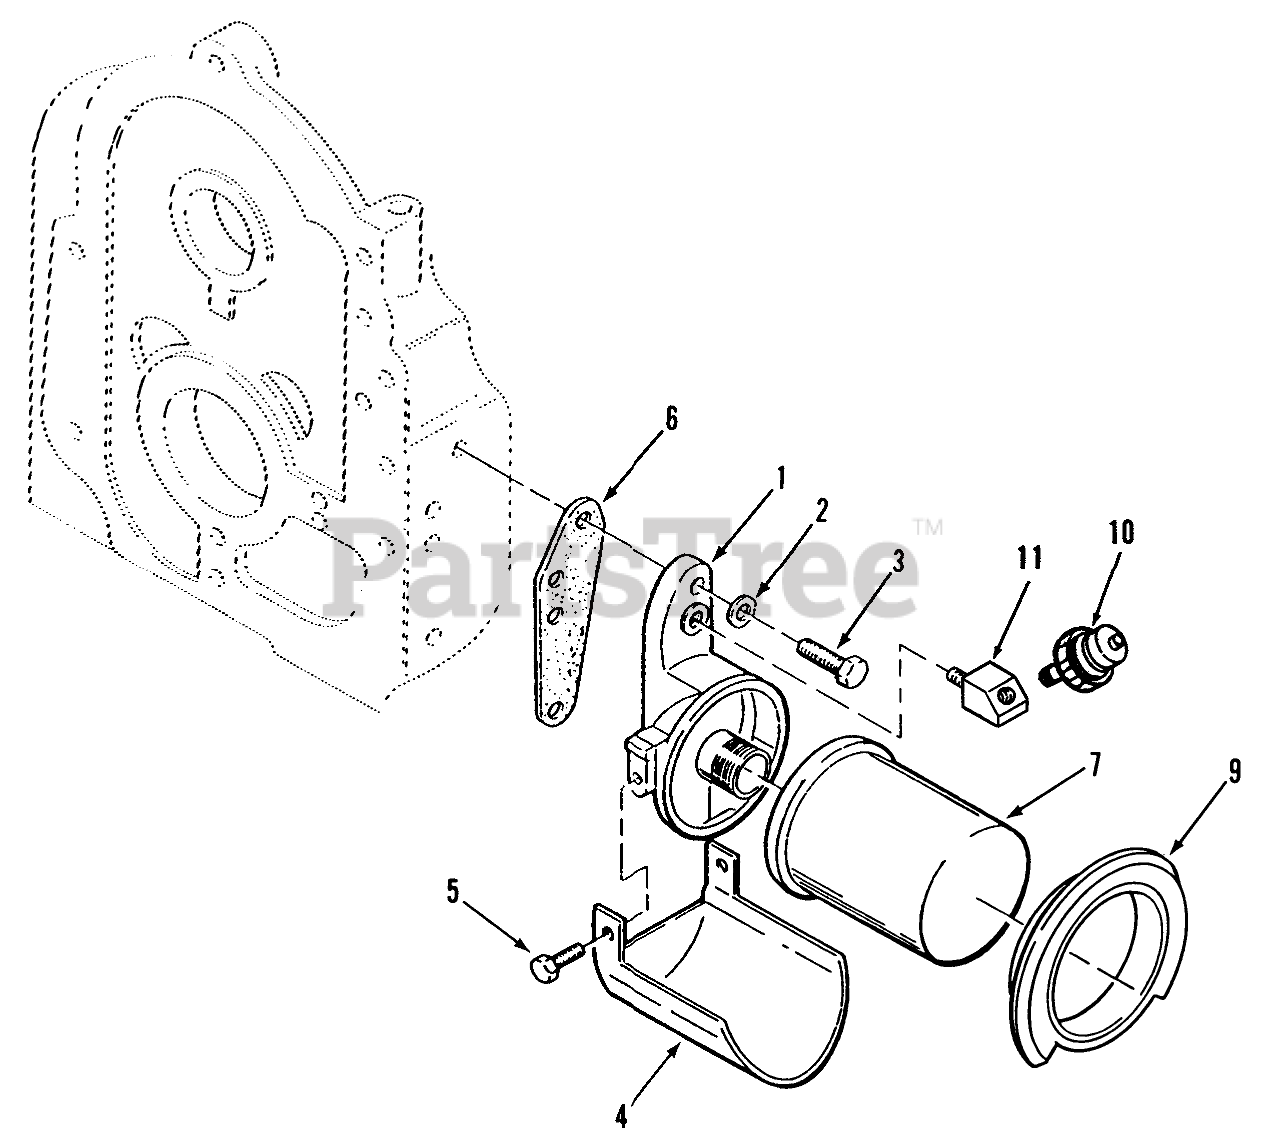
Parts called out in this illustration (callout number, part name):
1	ADAPTER-OIL FILTER
2	WASHER
3	SCREW - CAP HEX HEAD
4	OIL-FILTER DRAIN
5	SCREW-HH
6	Gasket
7	Oil Filter
10	Switch, Low Oil Pressure
11	ELBOW-45 DEG
15	GASKET - AIR SEAL
